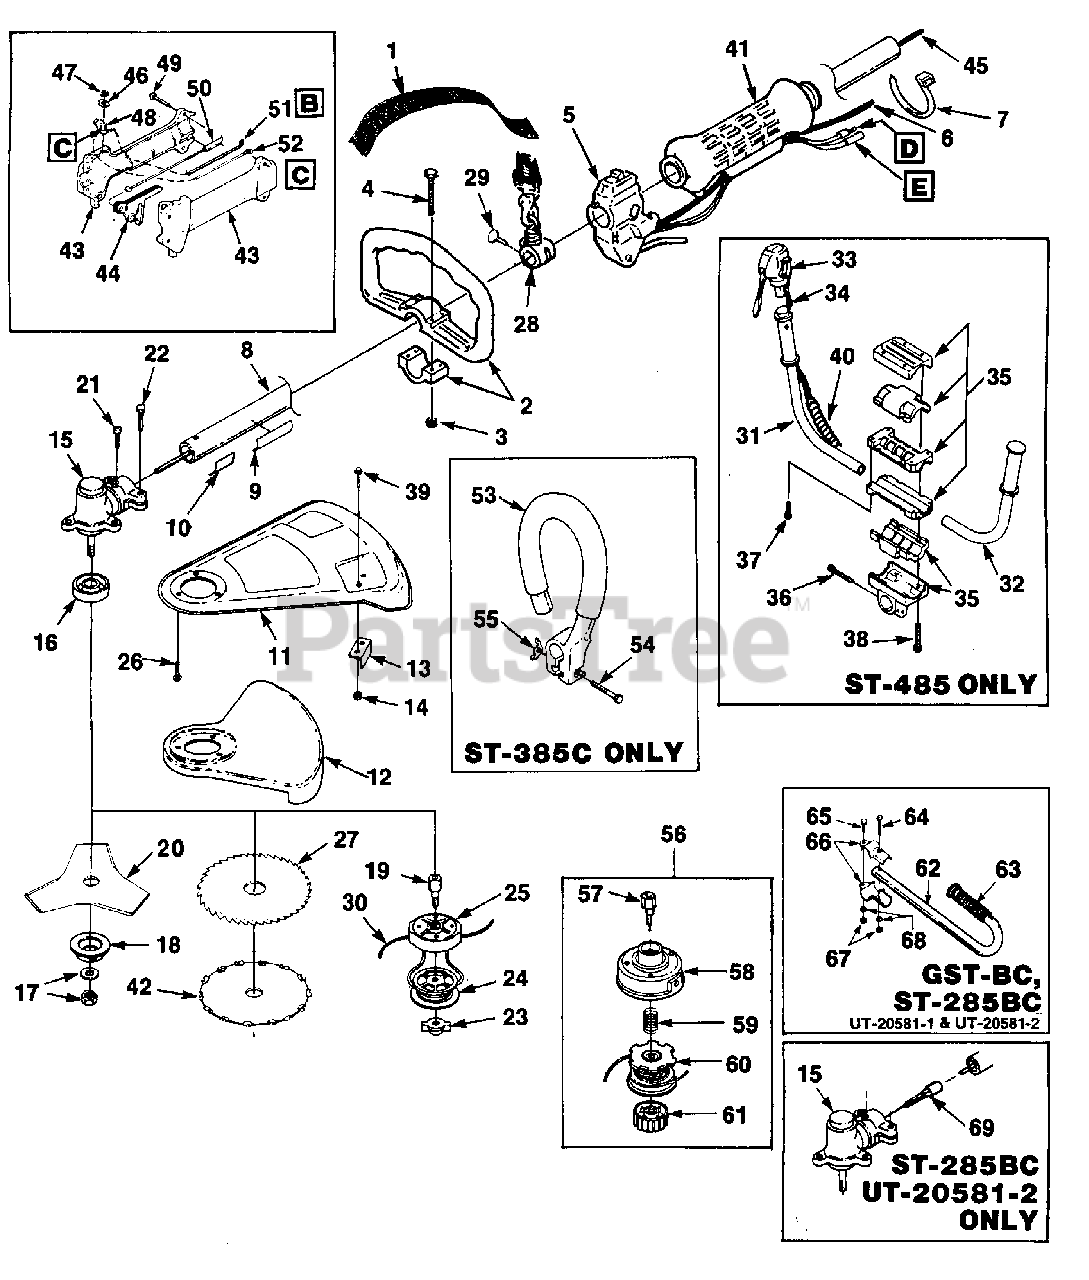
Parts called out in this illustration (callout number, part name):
1	HARNESS w/CONNECTOR
2	HANDLE (ST-385)
3	NUT (ST-385)
4	SCREW (ST-385)
5	THROTTLE & SWITCH w/Lead (ST-385)
6	THROTTLE CABLE (ST-385 & ST-385C)
7	CABLE- Tie
8	HOUSING- Drive Shaft (ST-385, ST-385C, ST-485)
9	DECAL- Starting Instructions
10	DECAL- Warning
11	DEFLECTOR- Grass
12	GUARD- Blade
13	BLADE- Cut-off
14	NUT (10-24)
15	GEAR HEAD ASSEMBLY
16	WASHER- Flange
17	NUT- Hex (L.H.)
18	WASHER- Flange
19	CONNECTOR- Drive
20	TRI-ARC BLADE
21	SCREW (10-24 x 1/2")
22	SCREW (10-24 x 1")
23	NUT- (L.H.)
24	SPOOL & STRING (Dual Line)
25	HOUSING & EYELET
26	SCREW (10-24 x 1/2")
27	BLADE- Saw (optional)
28	BRACKET- Hanger
29	SCREW (10-24 x 1/2")
30	LINE- Replacement (.095 Dia.) 1 lb. Box (250 Ft.)
31	HANDLE BAR (ST-485)
32	HANDLE BAR (ST-485)
33	THROTTLE & SWITCH w/lead (ST-485)
34	THROTTLE CABLE (ST-485)
35	HANDLE BRACKET (ST-485)
37	SCREW
38	SCREW
39	SCREW (10-24 x 3/8")
40	SLEEVING- Plastic (ST-485)
41	GRIP- Handle
42	BLADE- Saw 7" Machete (optional)
43	HANDLE GRIP ASSEMBLY
44	TRIGGER
45	DRIVE SHAFT (Solid)
46	PLATE- Indicating
47	NUT-
48	SWITCH- Toggle
49	SCREW- Plastite (#8 x 3/4")
50	CABLE- Throttle
51	LEAD- Electrical
52	LEAD- Ground
53	HANDLE & PAD (ST-385C)
54	SCREW- Hex hd. (ST-385C)
55	NUT- Wing (ST-385)
56	CONVERSION KIT
57	CONNECTOR- Drive (ST-385BC & ST-485)
58	HOUSING & EYELET (ST-385C & ST-485)
59	SPRING- Compression (ST-385C & ST-485)
60	SPOOL & STRING (ST-385C & ST-485)
61	RETAINER (ST-385C & ST-485)
62	HANDLE-"J" (GST-BC & ST-285BC)
63	GRIP (GST-BC & ST-285BC)
64	SCREW(1/4-20 x 1 1/2") (GST-BC & ST-285BC)
65	SCREW (1/4-20 x 1") (GST-BC & ST-285BC)
66	CLAMP- Handle bar (GST-BC & ST-285BC)
67	NUT (1/4-20) (GST-BC & ST-285BC)
68	WASHER (1/4") (GST-BC & ST-285BC)
69	ADAPTOR (ST-285BC, UT-20581-2)
